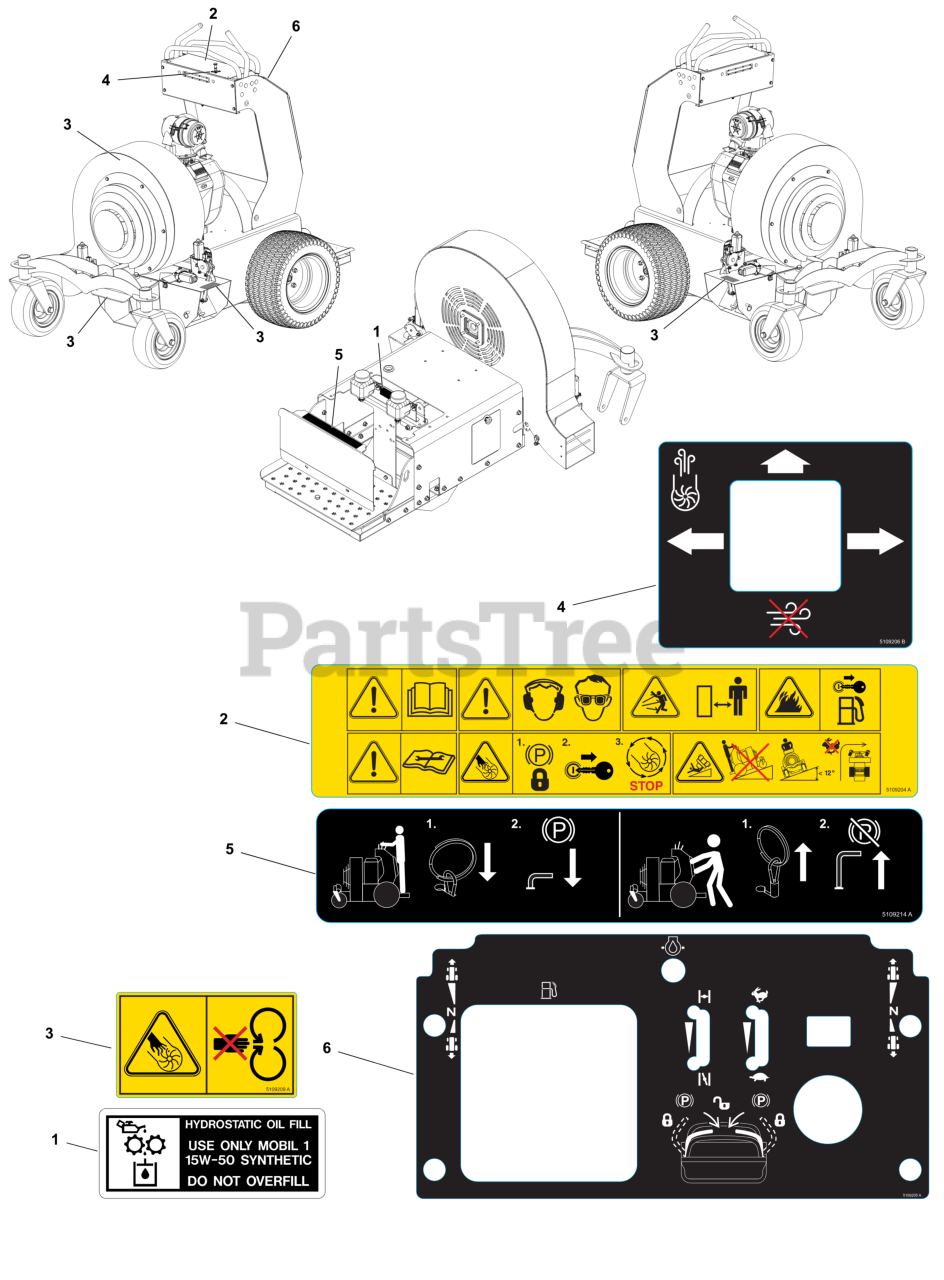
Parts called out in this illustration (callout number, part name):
2	DECAL, Warning/Safety
3	DECAL, DANGER
5	DECAL, BRAKE, PARK
6	DECAL, Controls
